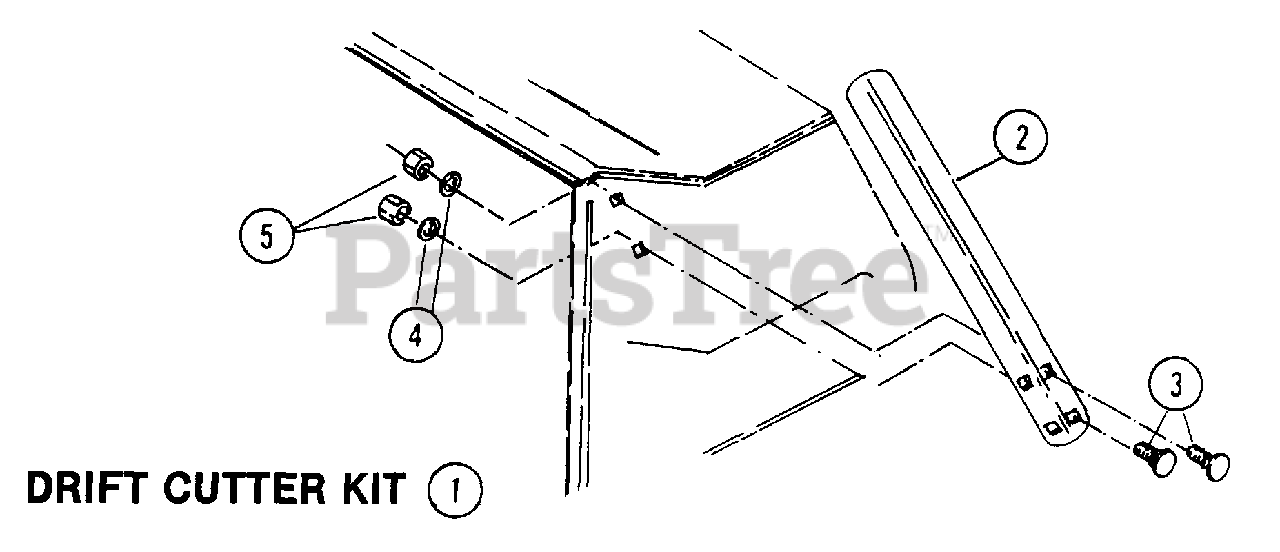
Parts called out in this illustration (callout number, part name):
1	KIT, Drift Cutter
2	CUTTER, DRIFT
3	BOLT, 5/16Cx3/4 Carriage
4	LOCKWASHER, 5/16 Split
5	NUT, 5/16 Hex
